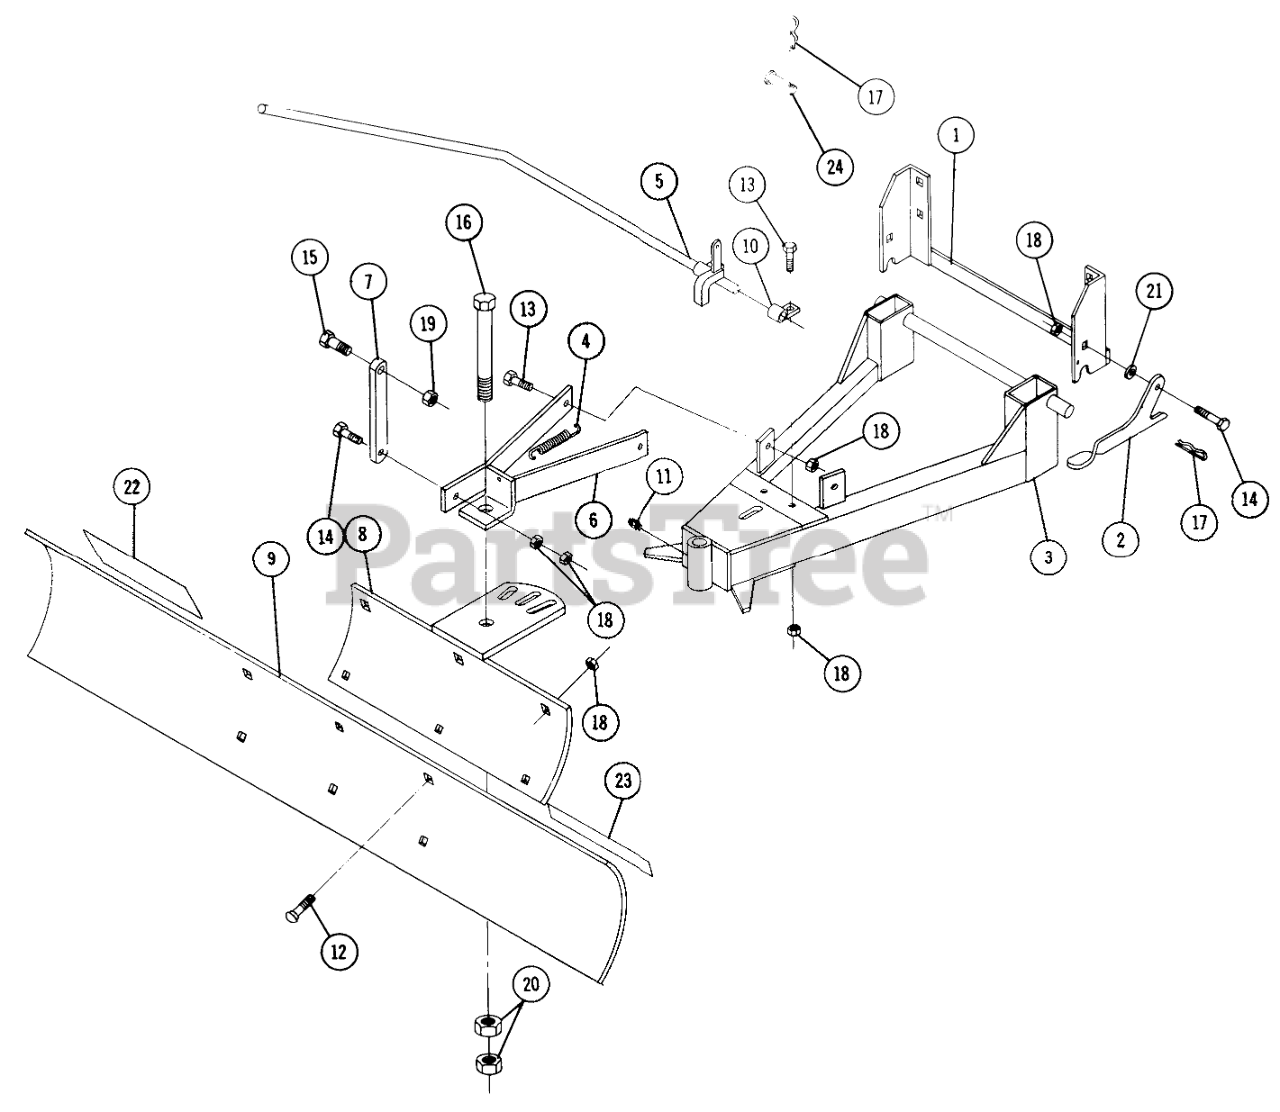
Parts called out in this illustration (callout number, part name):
1	Bracket
2	Latch Hitch
3	"A" Frame Assembly
4	Spring
5	Blade Index & Lock Lever
8	PIVOT&BLADE MT (A R
9	Blade
10	Bushing-Index Lever
11	Zerk
12	Bolt
13	BOLT
14	Bolt
15	Hhcs
16	BOLT 3/4-10X5
17	Hairpin Cotter
18	Nut
19	Eslok Nut
21	Washer
22	Caution Decal
23	DECAL-WHEEL HORSE
